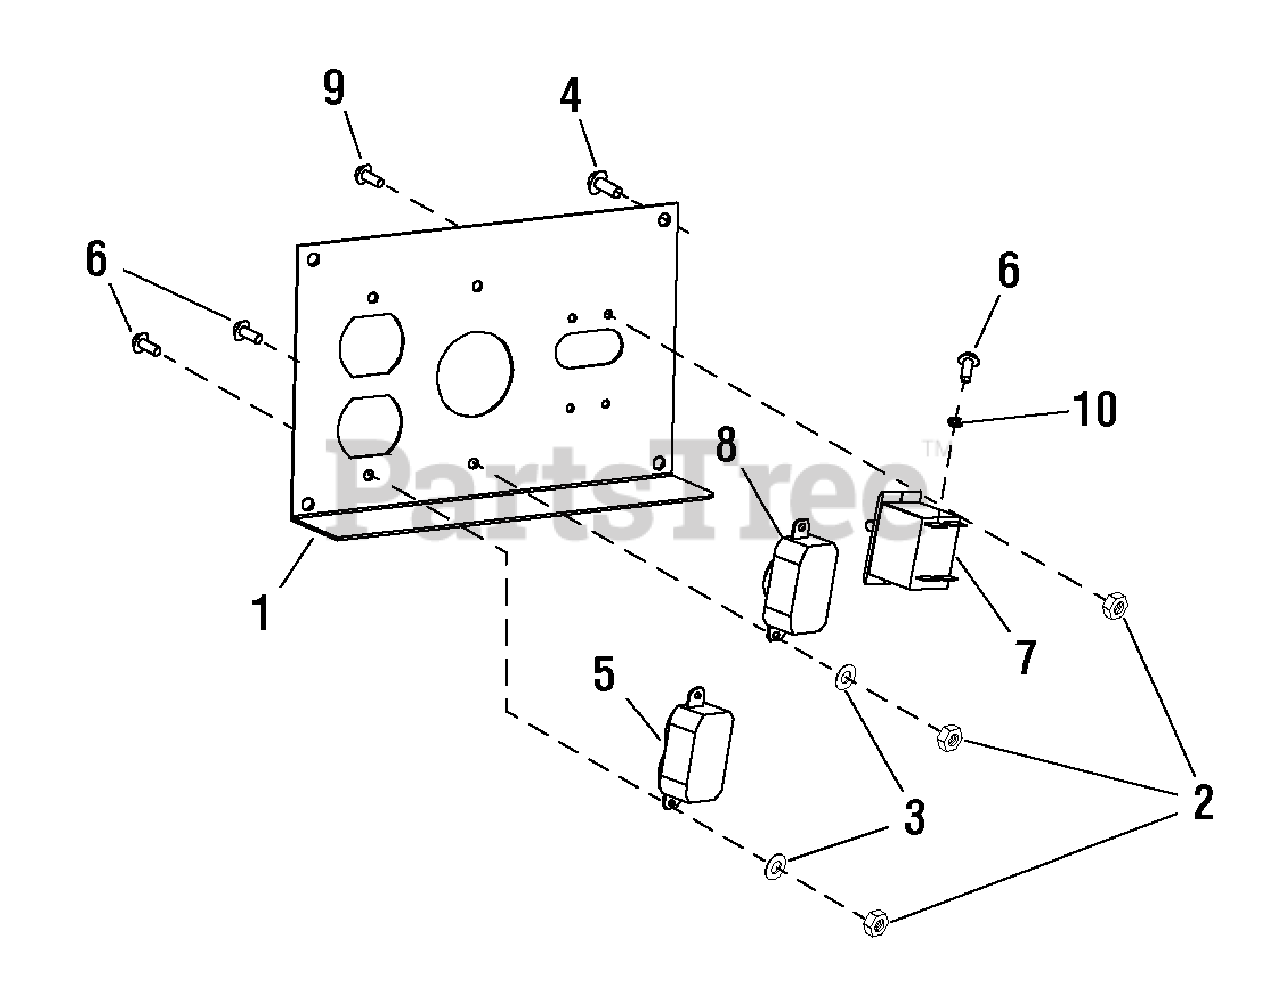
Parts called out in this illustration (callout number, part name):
1	CONTROL PANEL (Includes decal)
2	* NUT, Nylon
3	* WASHER, M4 x 08
4	* SCREW, M6 x 16
5	OUTLET, 120/125V, 15/20a, Duplex
6	* SCREW, Pan Head, M4x10
7	CIRCUIT BREAKER, 15A
8	OUTLET, 120/240V, 20a, Locking
9	* SCREW, M3 x 06
10	* LOCK WASHER
